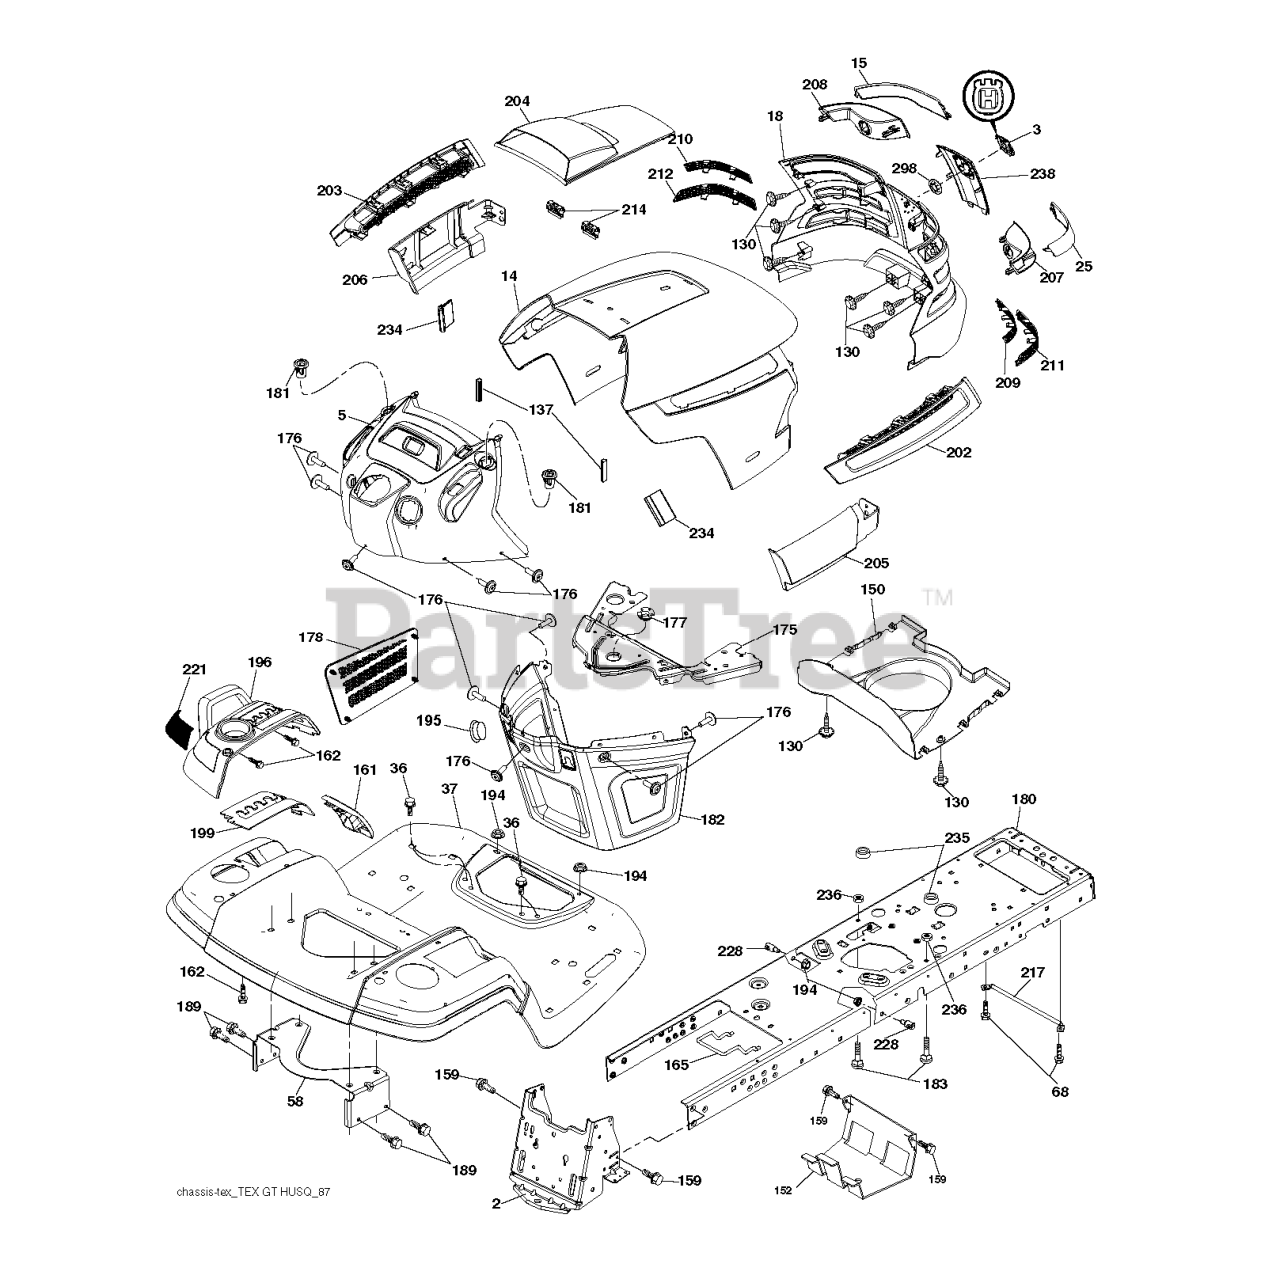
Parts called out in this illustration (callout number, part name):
2	DRAWBAR.STGT
3	RP LOGO
14	HOOD
15	LENS.LH.TEX.GT.HUSQ.CL
18	GRILL.ASM.HUSQ.TG/CRD.W/TRIM
25	LENS.RH.TEX.GT.HUSQ.CL
36	SCREW 5/16"
37	FENDER.PNT.TX.GT.CH/FW.ORANGE
58	BRKT.SUPPORT.FNDR/TANK
68	Screw 5/16-18 x 1/2 Hex, Self Tapping 5/16-18 x 1/2
130	SCREW.#10 X 0.750.BOS
137	BUMPER DASH
150	AIR.DUCT.HOOD.TEX.GT.HUSQ
152	SHIELD.BROWNING/DEBRIS
159	SCREW, 3/8-16X3/4
161	CONSOLE.FUEL.WINDOW.HU
162	SCREW.HI-LO.CONSOLE
165	SUPPORT.TANK.REAR.B/TE
175	PLATE.CROSSMEMBER.HUSQ
176	SCREW.#10-24X5/8.RN.QU
177	BUSHING, STEERING
178	CARGO.ASM.NET.TXGT.W/C
180	CHASSIS.STAMPING.LT/GT
181	BUSHING.MNT.FEND.CRGO.
182	DASH.LOWER.COMMON.12V.ADAPTOR
183	BOLT.5/16-18X1-1/4 FULL THD
189	SCREW
194	NUT LOCK HEX FLANGE 5/16-18
195	PLUG.HOLE.DASH.LOWER.12V.BLK
196	CONSOLE.ASM.DCKLFT.W/RF.HQ.DLR
199	PLATE.DECK.LIFT.HUSQVARNA.GT
202	VENT.SIDE.HOOD.HUSQ.RH.GREY
203	VENT.SIDE.HOOD.HUSQ.LH.GRAY
204	HOOD VENT
205	SKIRT.HOOD.SIDE.HUSQ.RH.GREY
206	SKIRT.HOOD.SIDE.HUSQ.LH.GREY
207	BEZEL.RH.TEX.GT.HUSQ
208	BEZEL.LH.TEX.GT.HUSQ
209	INSERT.HEX.GRILL.HUSQ.GREY
210	INSERT.HEX.GRILL.HUSQ.
211	INSERT.HEX.GRILL.HUSQ.
212	INSERT.HEX.GRILL.HUSQ.
214	CLIP.RETAINER.TINNER.
217	ROD.PIVOT.HOOD
221	REFLECTOR.LH.TEX GT HU
228	STUD.FASTNER.W/ANTI-ROTATE
234	BUMPER.HOOD.TEX.HUSQVARNA
235	SPACER FENDER
236	NUT.CENTERLOCK.5/16-
238	TRIM.HUSQ.TG/CRD.SERVICE
298	NUT PUSH M
